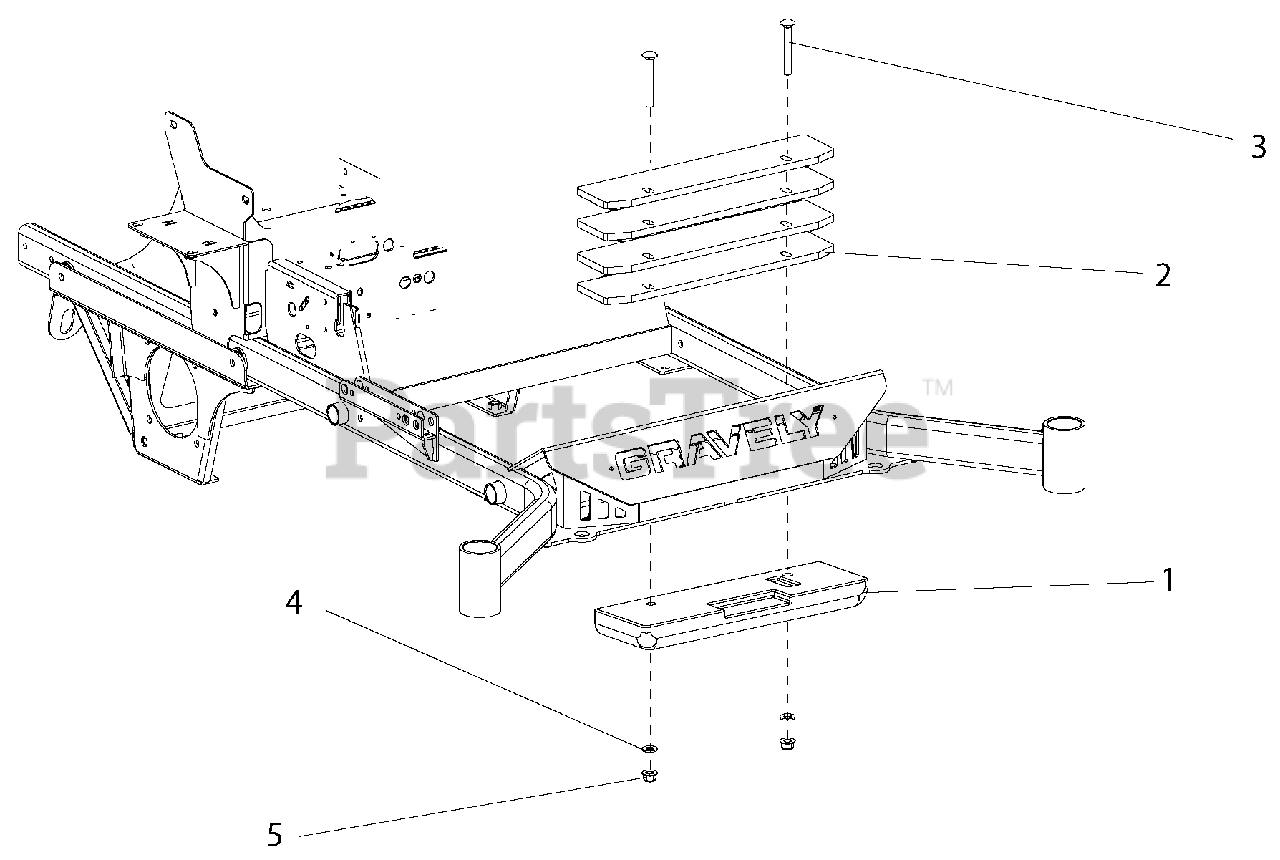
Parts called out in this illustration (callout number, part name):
1	WEIGHT, CAST IRON
2	PLATE, COUNTER WEIGHT
3	BLT-RDHDSQNK .50-13X5.00 G5YZ
4	WSHR-FL-STL .531X1.06X.095 YWZC
5	NUT-LK-NYL-FLG .50-13 YWZC
